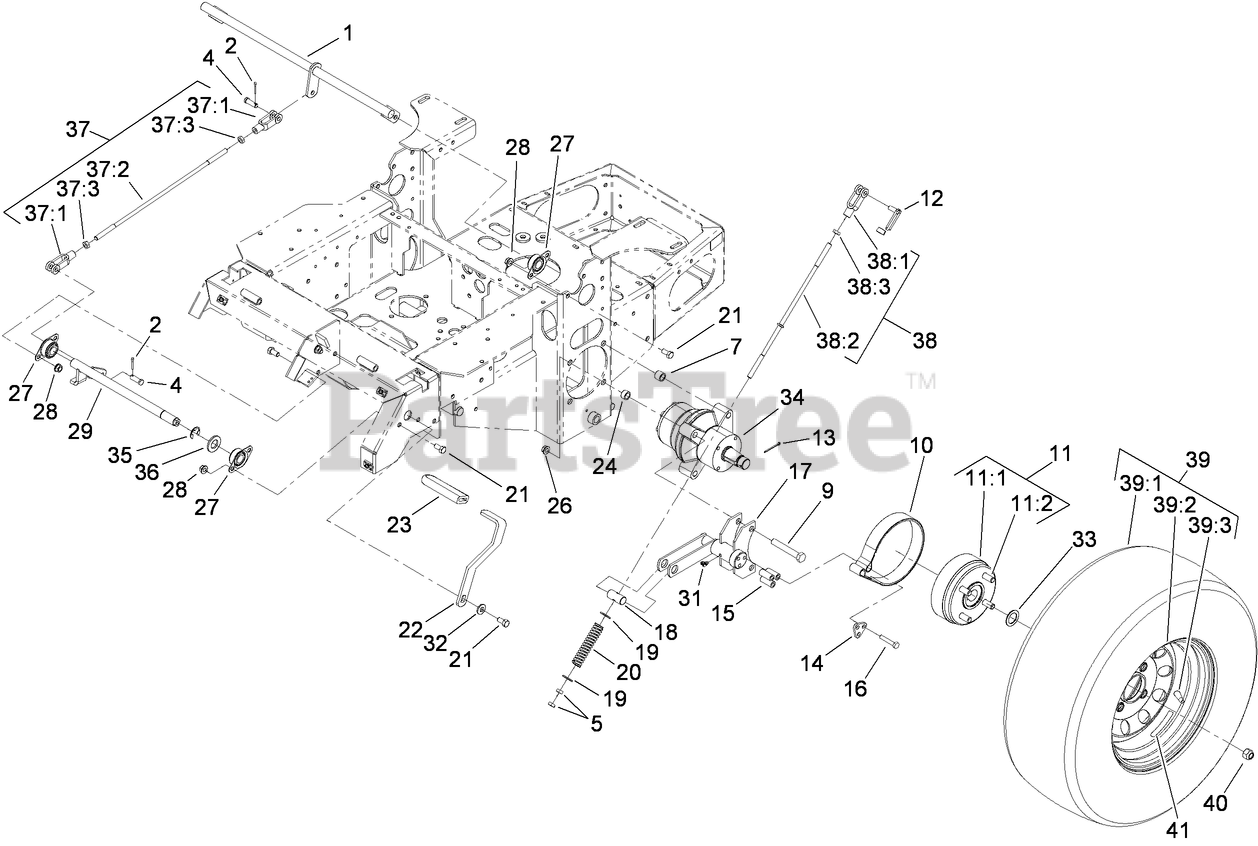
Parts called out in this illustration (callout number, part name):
1	CRANK-BRAKE, PARK
2	PIN-COTTER
4	PIN-CLEVIS
5	NUT-HEX
7	SPACER-WHEEL
9	SCREW-HH
10	BAND-BRAKE
11	WHEEL HUB ASM
11:1	HUB-WHEEL
11:2	STUD-WHEEL
12	Pin-Spring, Clevis
13	PIN-COTTER
14	RETAINER-BAND, BRAKE
15	SPACER
16	SCREW-HH
17	BRACKET-BRAKE
18	PIN-TRUNION
19	WASHER-FLAT
20	SPRING-BRAKE
21	SCREW-HH
22	HANDLE-BRAKE, PARK
23	GRIP-LEVER
24	SPACER-WHEEL
26	NUT-HHF
27	BEARING-FLANGE, SIDE
28	NUT-HHF, WHIZ
29	Shaft-Brake, Parking
31	FITTING-GREASE
32	WASHER-BELLEVILLE
33	WASHER-SPACER
34	MOTOR-WHEEL
35	E-RING
36	WASHER-FLAT
37	BRAKE ROD ASM
37:1	YOKE-LINKAGE, BRAKE
37:2	LINKAGE-HANDLE, BRAKE
37:3	NUT-HEX
38	BRAKE ROD ASM
38:1	YOKE-LINKAGE, BRAKE
38:2	ROD-BRAKE
38:3	NUT-HEX
39	WHEEL AND TIRE ASM
39:1	TIRE
39:3	STEM-VALVE
40	NUT-LUG
41	DECAL
